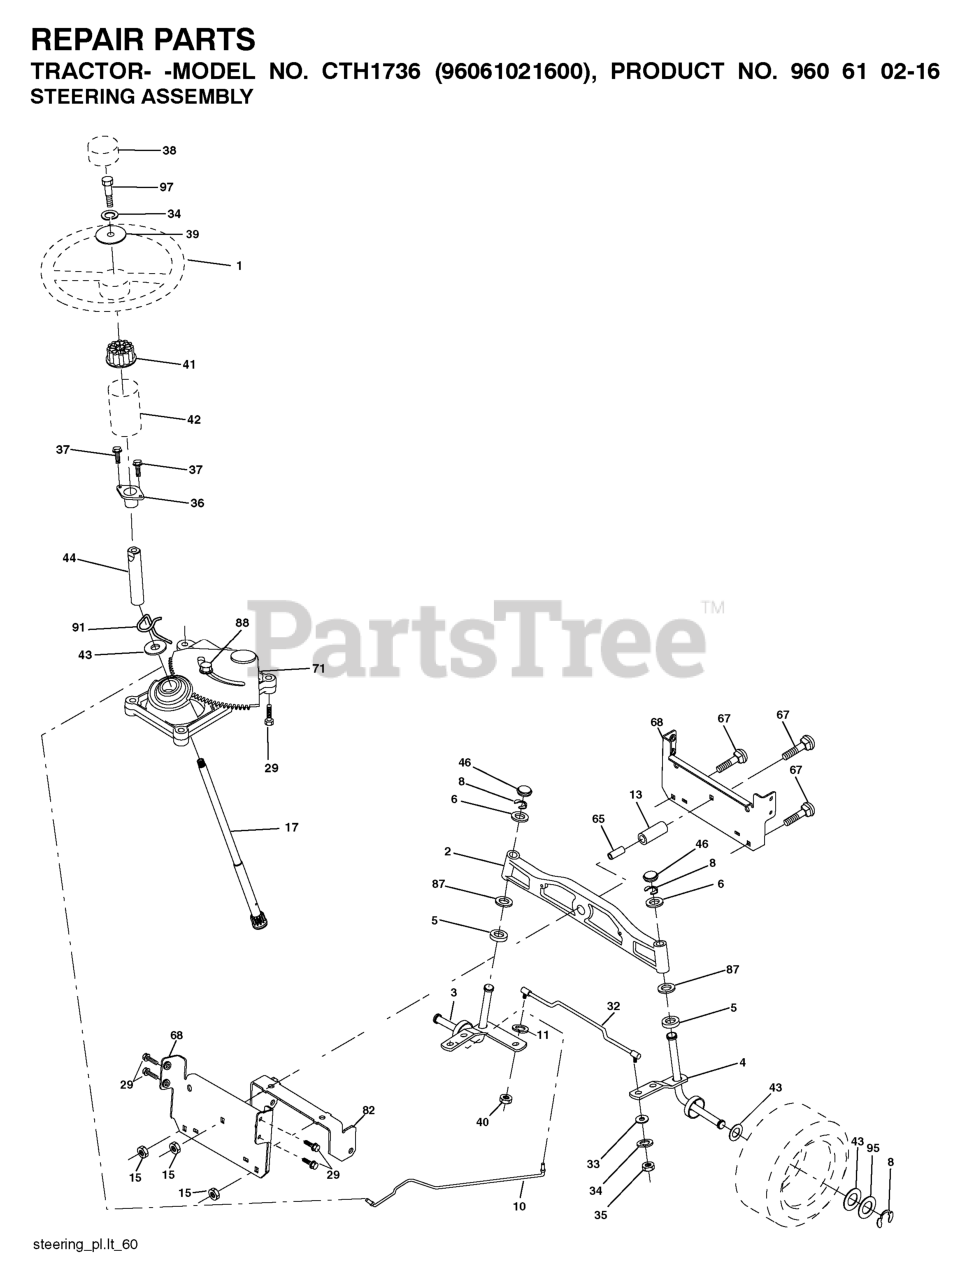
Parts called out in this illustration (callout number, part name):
1	STEERING WHEEL
2	AXLE ASSY FRONT
3	SPINDLE.ASM.LH.15"TIRES
4	SPINDLE.ASM.RH.15"TIRES
5	THRUST WASHER
10	DRAGLINK.15".TIRES.2001
11	WASHER, LOCK 3/8
13	TUBE, PIVOT AXLE
15	NUT
17	SHAFT STEERING SPLINE
29	SCREW, 3/8-16X3/4
33	WASHER M
34	WASHER.LOCK.HVY.HLCL.SPR.5/16
35	NUT, CROWNLOCK
36	BUSHING, STEERING
37	SCREW.TT.#10-32X.5.3/8.FLANGE
38	INSERT.CAP.STRG.WH.GRAY
39	WASHER.11/32
40	NUT CROWNLOCK 3/8-24
41	ADAPTER, WHEEL STNG..
42	BOOT, STEERING
44	SHAFT.EXTEN.STRG.SPLINE
46	CAP.SPINDLE.BLACK
65	SPACER BRACE AXLE
67	BOLT CARRIAGE
68	BRACE.AXLE.15"TIRES
71	STEERING ASM
82	BRACKET.SUSP.CHASSIS.FRONT.15
87	WASHER, FLAT .781 X 1 1/2"
88	BOLT, SHOULDER 7/16-20
91	CLIP.STEERING
95	WASHER.HARDENED
